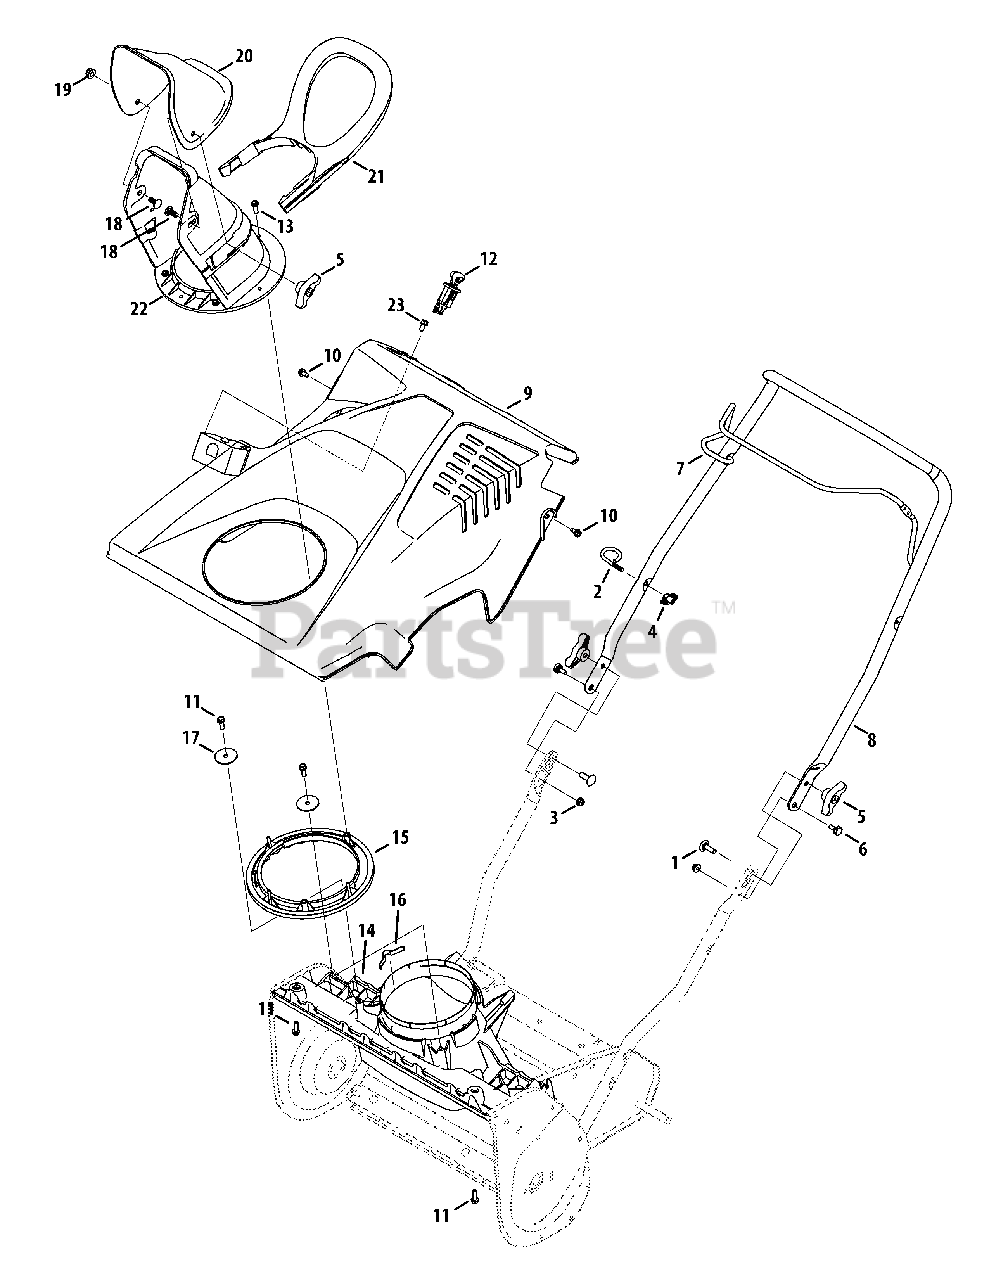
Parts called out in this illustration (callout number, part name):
1	Carriage Bolt, 5/16-18 x 1.00
2	Eye Bolt, 1/4-20
3	Flange Lock Nut, 1/4-20
4	Knob Handle
5	Wing Knob
6	Shoulder Screw, .375 x .148 x 1/4-20
7	Auger Bail
8	Upper Handle
9	Top Cover (Black w/o electric start)
9	Top Cover (Gray)
9	Top Cover (Black)
10	Hex Screw, 1/4-14 x .500
11	Screw, Hi-Lo:1/4-15, 0.75
12	Ignition Switch Assembly
13	Hex Washer Screw, 1/4 x .750
14	Chute Adapter
15	Chute Ring
16	Chute Adjustment Spring
17	Flat Washer, .28 x 1.5 x .066
18	Carriage Bolt, 5/16-18 x .750
19	Flange Lock Nut, 5/16-18
20	Upper Chute
21	Chute Handle
22	Lower Chute
23	Hex Washer Screw, 1/4-15 x .50
